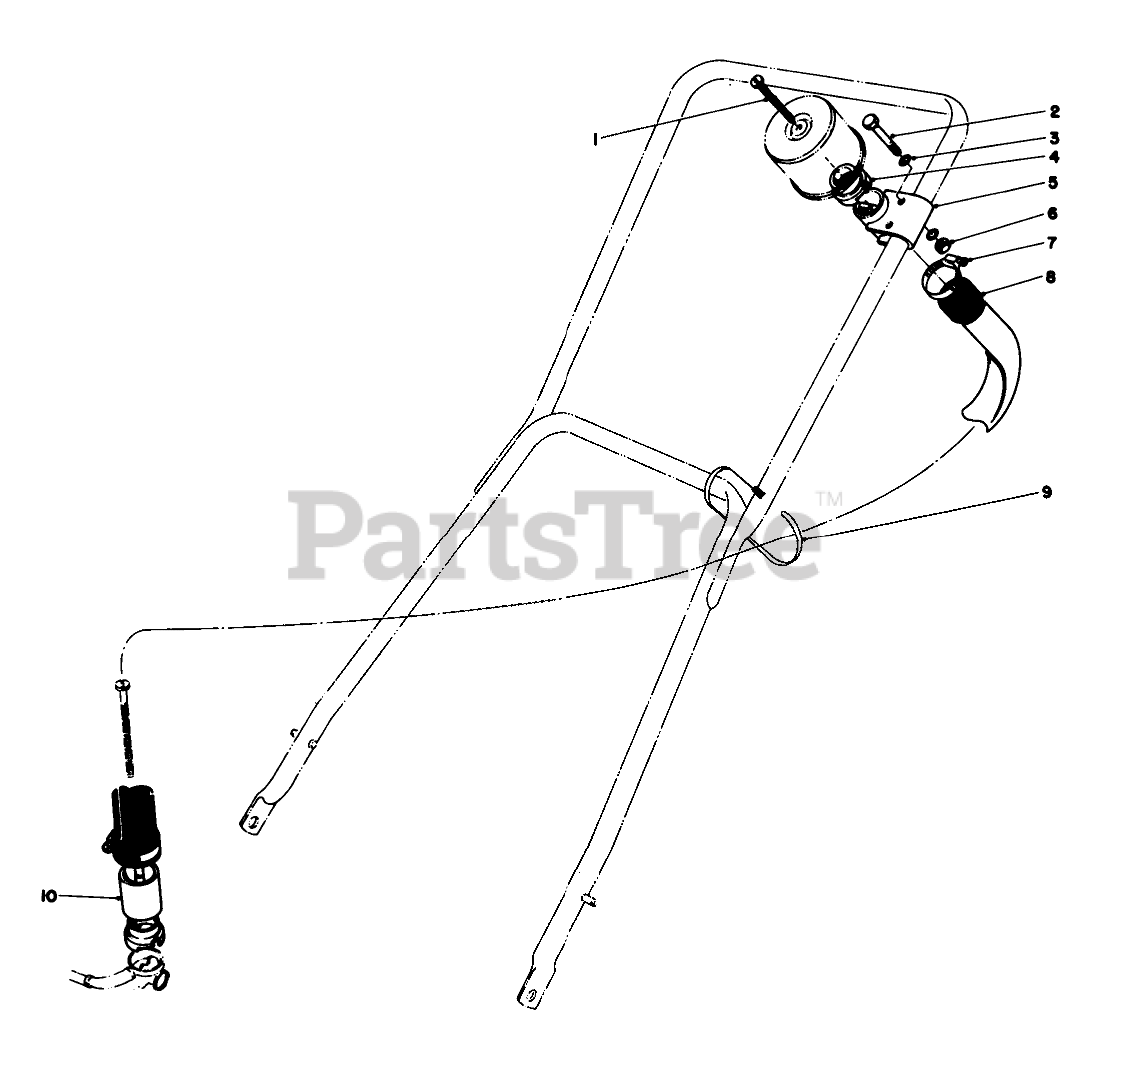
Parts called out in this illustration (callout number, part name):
1	Pan Hd. Machine Screw
2	SCREW-HH
3	WASHER-PLAIN
4	GASKET
5	Mounting Bracket Air Cleaner
6	NUT-HEX
7	CLAMP-HOSE
8	Hose Air Cleaner
9	TIE-CABLE
10	HOSE COUPLING WA B
